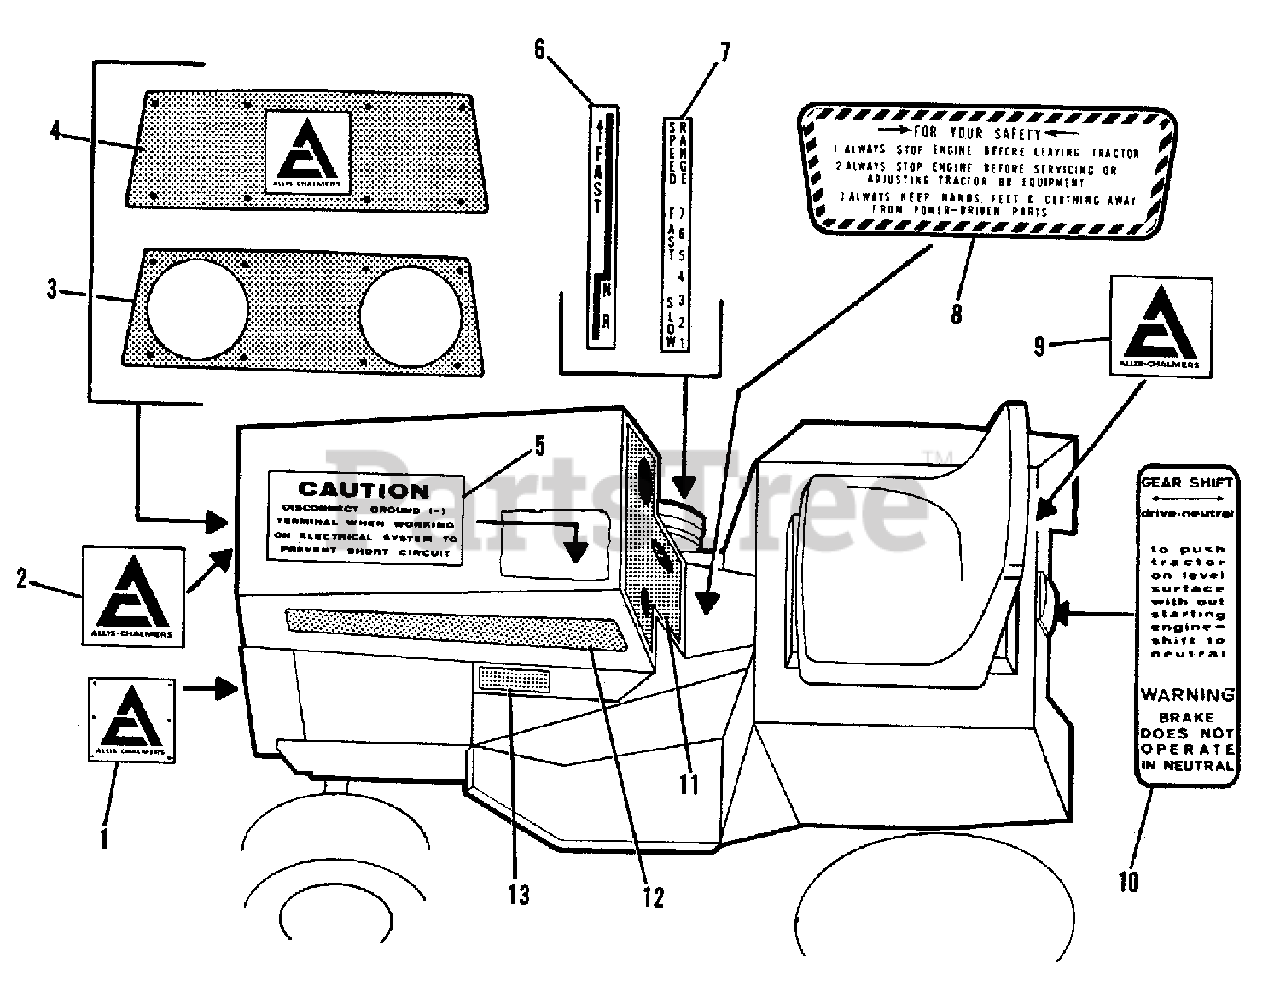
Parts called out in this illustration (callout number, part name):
1	PLATE, Name (Models 312-H, 314-D & 314-H
2	DECAL, Trademark (Models 310, 312 & 314)
3	DECAL, Head Light Cover( Models 312-H, 314-D & 314-H)
4	DECAL, Cover (Models 310-D & 312-D)
5	DECAL, Caution
6	DECAL, Quadrant (Models 312-H & 314-H)
7	DECAL, Quadrant (All Models Except Hydrostatic)
8	DECAL, Safety
9	DECAL, Trademark
10	DECAL, Safety Film (Models 312-H & 314-H)
11	DECAL, Instrument Panel (Models 310, 312 & 314)
11	DECAL, Instrument Panel (Models 310-D, 312-D & 314-D)
11	DECAL, Instrument Panel (Models 312-H & 314-H)
12	DECAL, L.H. A-C Hood (Allis Chalmers)
12	DECAL, R.H. A-C Hood (Allis Chalmers)
12	DECAL, R.H. Hood (310)
12	DECAL, L.H. Hood (310)
12	DECAL, R.H. Hood (312)
12	DECAL, L.H. Hood (312)
12	DECAL, R.H. Hood (314)
12	DECAL, L.H. Hood (314)
13	DECAL, Deluxe (310-D, 312-D & 314-D)
13	DECAL, Hydrostatic (312-H & 314-H)
14	DECAL, Lift Lever Instruction
